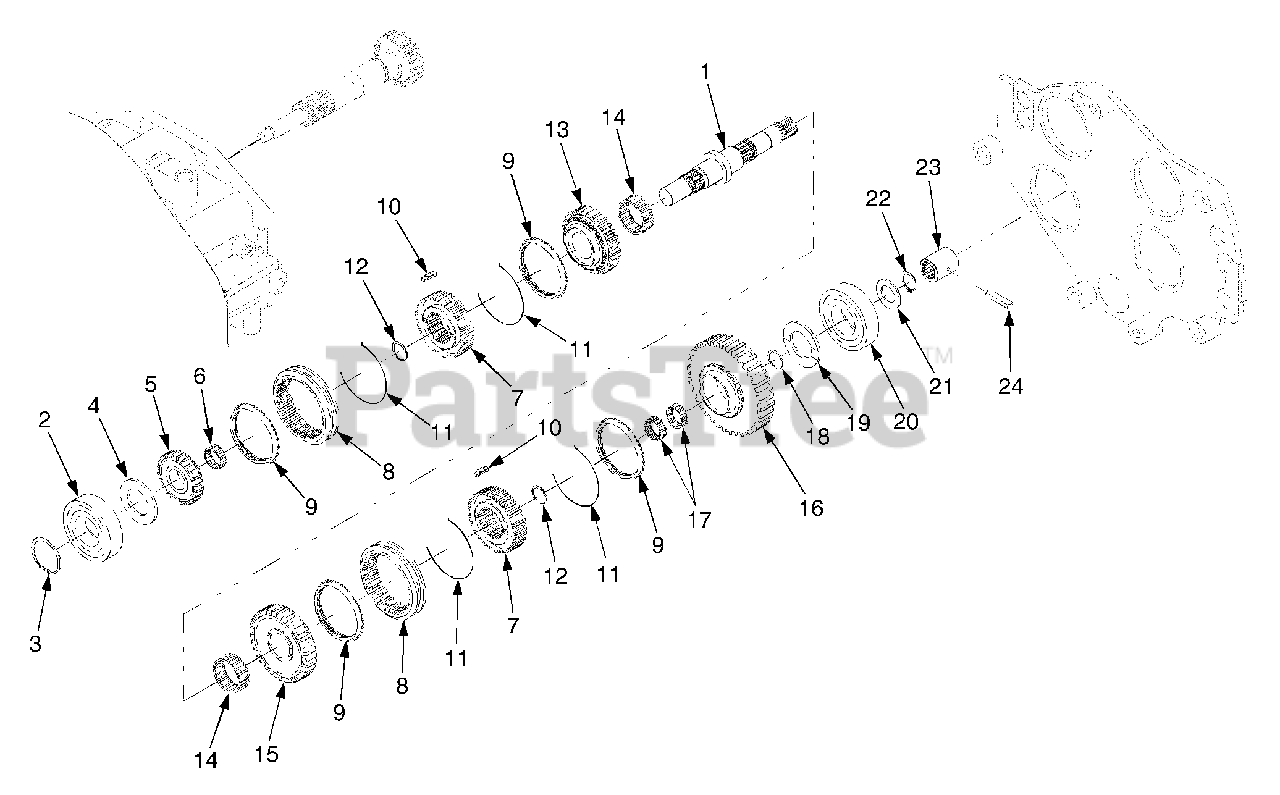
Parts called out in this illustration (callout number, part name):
1	Shaft, Counter
2	Bearing, Ball
4	Collar, Thrust
6	Bearing, Needle
8	Shifter
9	Ring, Synchronize
10	Key, Synchronize
14	Bearing, Needle
17	Bearing, Needle
19	Collar, Thrust
20	Bearing, Ball
